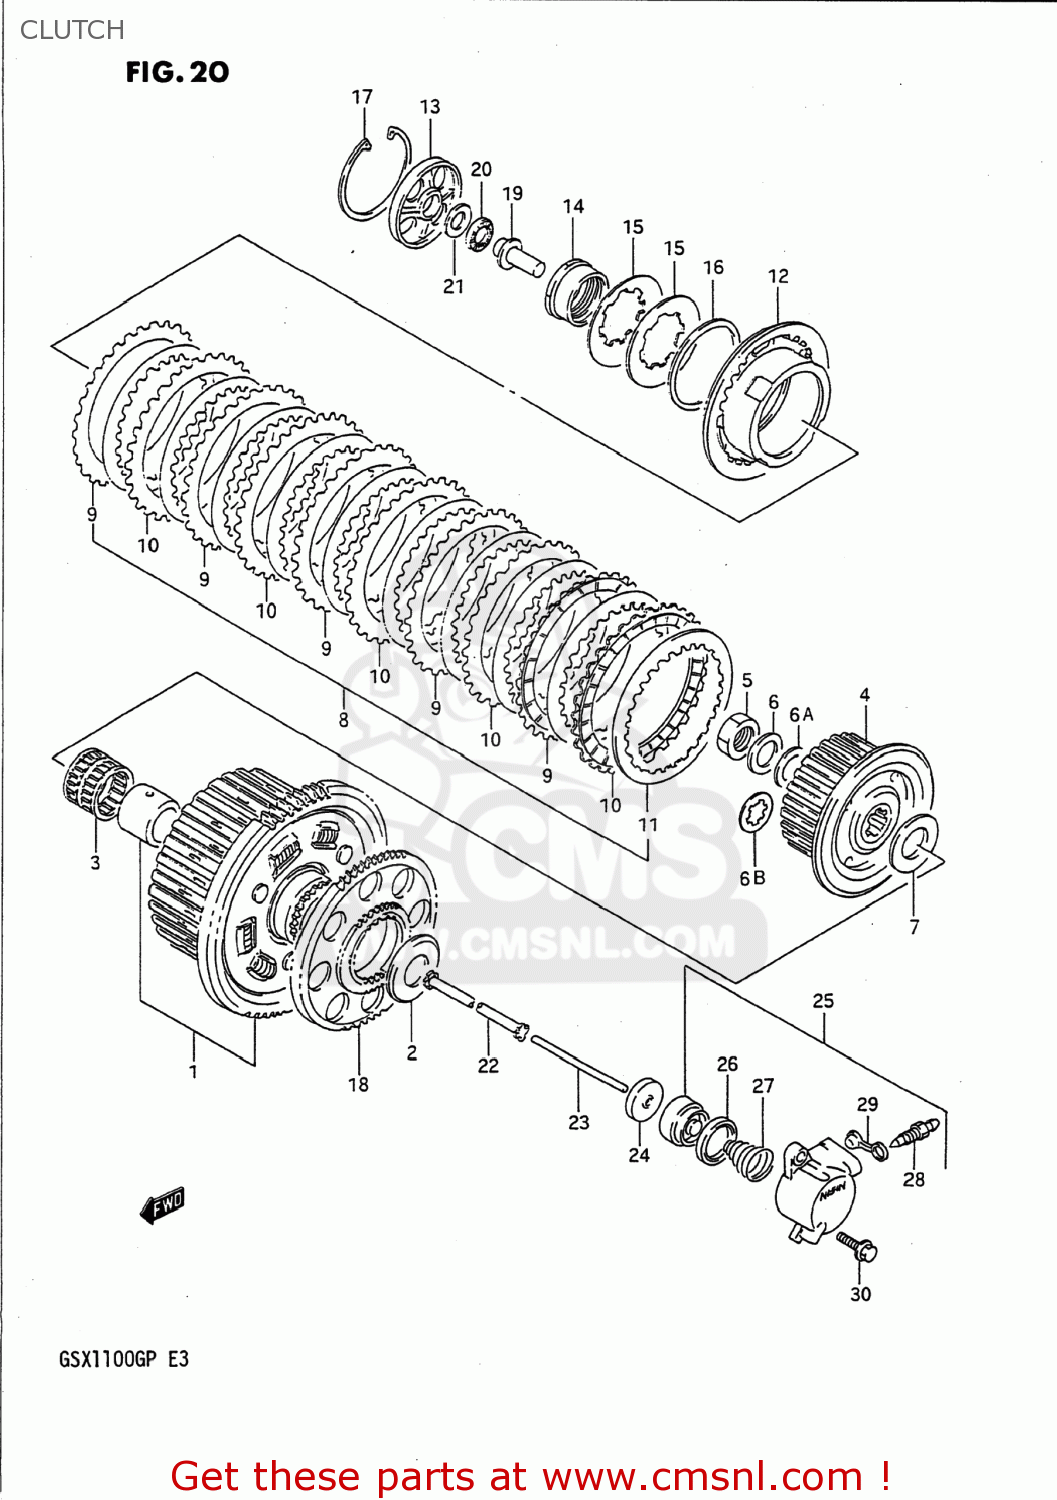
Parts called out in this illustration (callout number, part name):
1	GEAR ASSEMBLY,PRIMARY DRIVE
2	WASHER(25X54X2.5)
3	BEARING(35X40X35.8)
4	HUB,CLUTCH SLEEVE
5	NUT
6	WASHER
6A	SHIM
6B	WASHER,LOCK
7	WASHER(25X50X2.5)
8	PLATE ASSY,CLUTCH
9	PLATE,CLUTCH DRIVE (NAS)
10	PLATE,CLUTCH DRIVE NO.1 (NAS)
11	PLATE,CLUTCH DRIVEN (NAS)
12	DISC,CLUTCH PRESSURE
13	LIFTER,CLUTCH PRESSURE DISC
14	HOLDER,CLUTCH SPRING
15	WASHER
16	SEAT,CLUTCH SPRING
17	CIRCLIP
18	GEAR,GENERATOR DRIVE
19	PIECE,CLUTCH PUSH
20	BEARING(15X28X2)
21	WASHER
22	ROD,CLUTCH PUSH,R
23	ROD,CLUTCH PUSH,L
24	SEAL,OIL(6X34X5.5)
25	CYLINDER,CLUTCH RELEASE
26	CUP
27	SPRING,CLUTCH CYLINDER
28	BLEEDER
29	CAP,BLEEDER
30	BOLT
